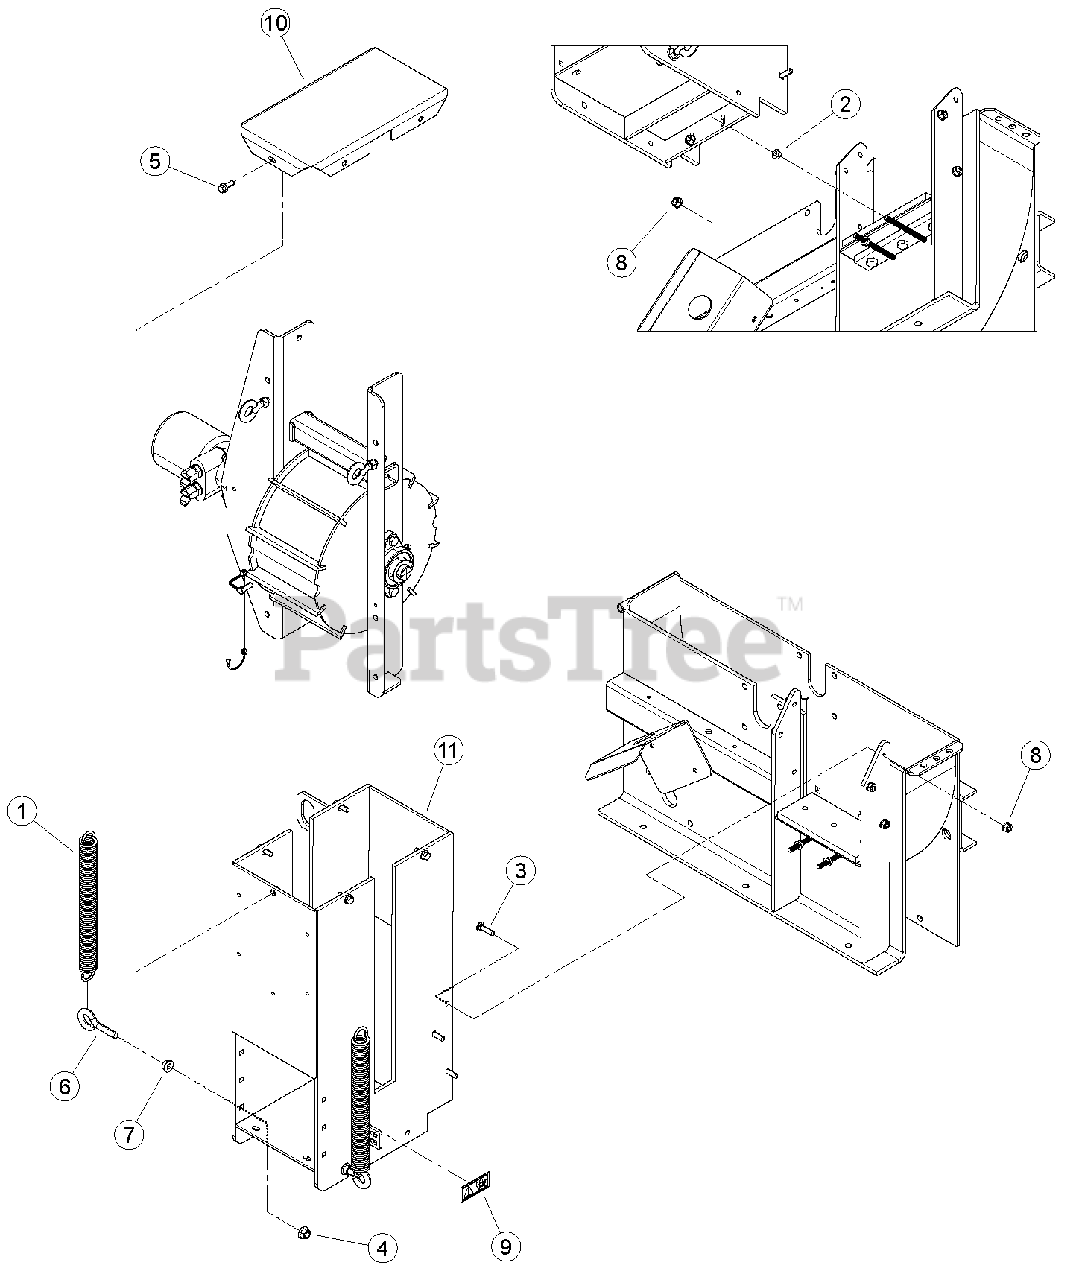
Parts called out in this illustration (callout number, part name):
1	SPRING, EXTENSION
2	NUT, 3/8" SERRATED FLANGE NC ZP
3	BOLT, 3/8 X 1-1/2" GR5 CRG NC ZP
4	NUT, 1/2-13 NYLOCK FLANGE
5	BOLT, 3/8 X 1 FLANGE NC
6	EYEBOLT, 1/2 X 2" ZP
7	NUT, 1/2 SPIRAL LOCK NC ZP
8	NUT, 3/8-16 NYLOCK FLANGE
9	DECAL, CRUSHING ISO
10	WELDMENT, TOP ROLLER COVER
11	WELDMENT, ROLLER SUPPORT
